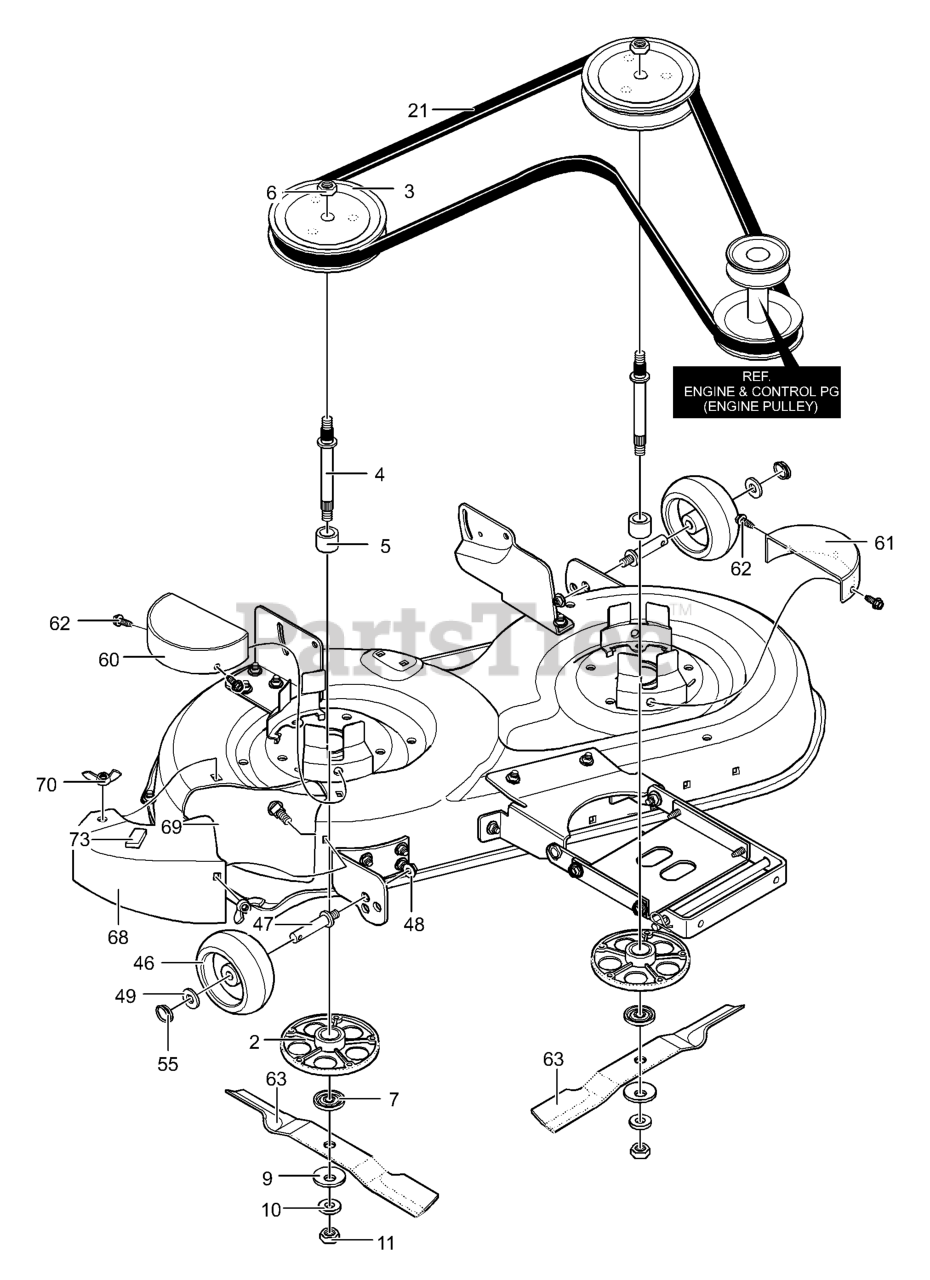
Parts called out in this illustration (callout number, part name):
2	HOUSING, JACKSHAFT
4	JACKSHAFT
6	NUT, 9/16-18
7	ADAPTER, BLADE
46	WHEEL, GAUGE
48	NUT,3/8-16
55	PIN, CIRCLE
60	GUARD, Belt R.H.
61	GUARD, Pulley L.H.
62	SCREW
63	BLADE
68	COVER, DISCHARGE
69	BOLT
70	NUT, WING
73	PAD, ADHESIVE
